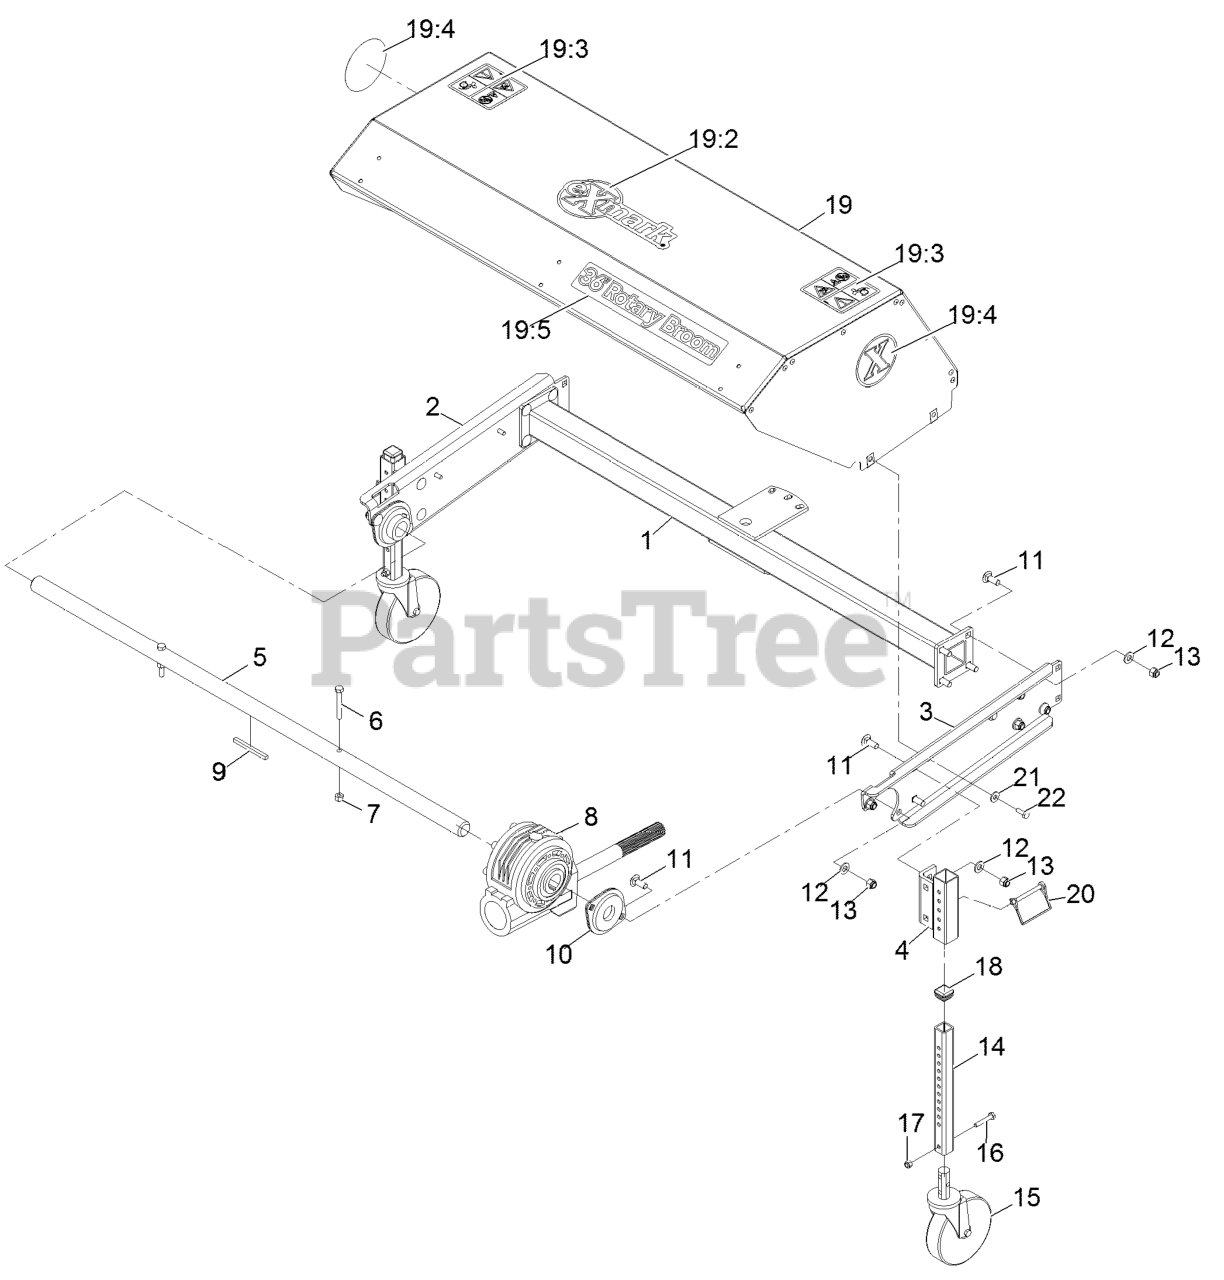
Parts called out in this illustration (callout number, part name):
2	ARM-RIGHT
3	ARM-LEFT
4	CASTER-BRACKET
6	SCREW-HH
7	NUT-LOCK, NI
8	GEARBOX-WORM
9	KEY-STRAIGHT
10	BEARING-FLANGE
11	BOLT-CARR
12	WASHER-FLAT
13	NUT-LOCK, NI
14	TUBE-SQUARE, HEIGHT ADJUS
15	CASTER-WHEEL
16	SCREW-HH
17	NUT-LOCK, NI
19	BROOM HOOD ASM
19:2	DECAL, EXMARK LOGO
19:3	DECAL-WARNING
19:4	DECAL-EXMARK X-LOGO 3.85
19:5	DECAL-36 ROTARY BROOM
20	PIN-WIRE, LOCK
21	WASHER-FLAT
22	SCREW-HH
